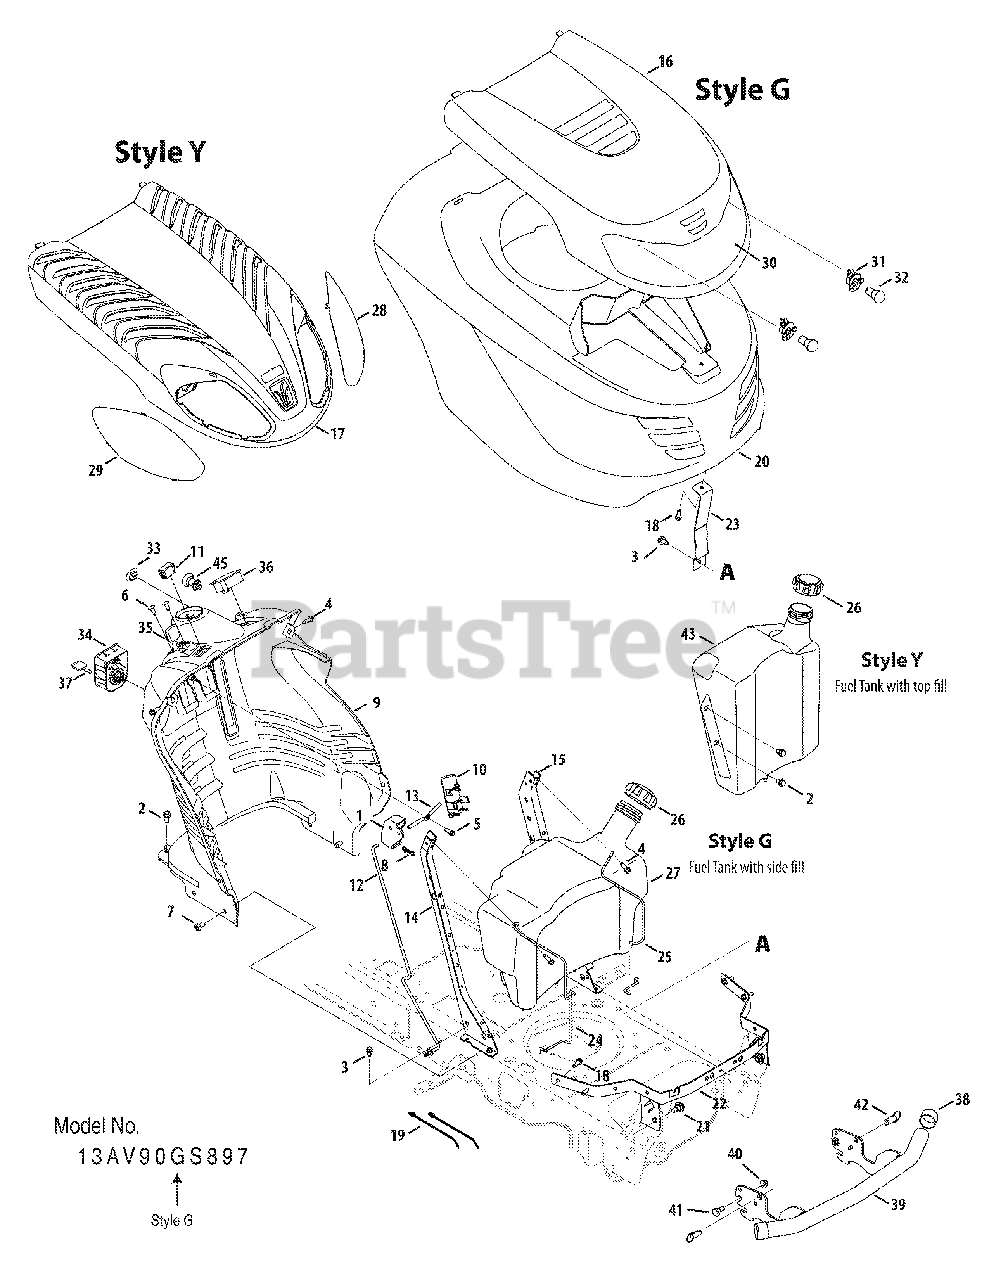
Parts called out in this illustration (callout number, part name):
1	Dash Lever
2	S-Tapp Screw 5/16-18 x .75
3	Hex Wash S-Tapp Screw 1/4-20 x .50
4	Hex TT Screw 1/4-20 x .75
5	Hex Tapp Screw 1/4 x .75" Lg.
6	Torx Mach. AB-Tapp Screw. 1/4-14 x .625 Lg
7	Screw 5/16-18 x .75
8	Bow-Tie Cotter Pin
9	Dash Panel (Elect. PTO w/ fuel level window)
10	Cruise Cover Y/G Style
11	Light Switch Cap
12	Latch Control Rod
14	RH Dash Support Plate
15	LH Dash Support Plate
16	Upper "G" Style Hood
17	Upper "Y" Style Hood
18	Screw, Bos, 1/4 Dia. x .75
20	G Style Hood (w/side fill fuel tank)
21	Shoulder Screw .43 x .29, 5/16-18
22	Hood Pivot Bracket
23	Hood Support Bracket
24	Tank Support Rod RH
25	Tank Support Rod LH
26	Cap-Fuel
27	Fuel Tank 2.75 Gal. (side fill)
28	Lens LH - Style "Y"
29	Lens RH - Style "Y"
30	Lens (Style G)
30	Reflector La bel
31	Socket
32	Miniature Lamp 12V Socket Type
34	Key Switch Module
35	Throttle/Choke Cont. Cable 25" Lg.
36	Am Meter
37	Ignition Key w/Plastic Cover
40	Hex Lock-Nut 3/8-16 Gr.B
41	Shoulder Screw. .498 x .340: 3/8-16
42	Quick Pin 1/2" dia. x 0.50
43	Fuel Tank 2.0 Gal. (top fill)
43	Fuel Tank 3.0 Gal. (top fill)
44	Extension Spring (w/Electric PTO only)
45	Electric PTO Switch
